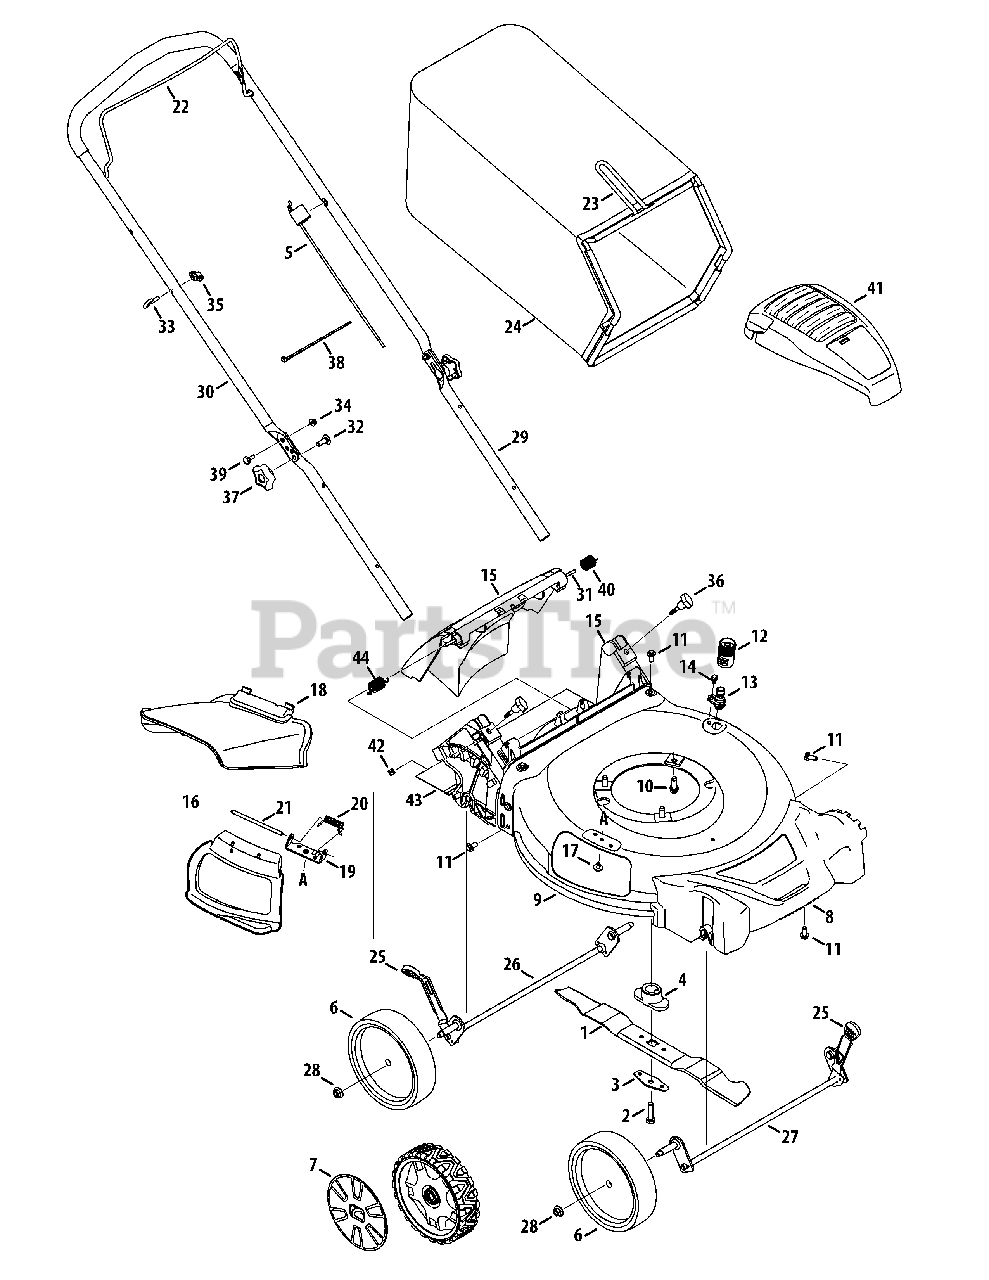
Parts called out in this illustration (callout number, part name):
1	Mulching Blade
2	Screw, 3/8-24 x 1.50
3	Blade Bell Support
4	Blade Adapter
5	Control Cable
6	Wheel, 8 x2
8	Front Cover
9	21" Deck
10	Screw, tt, 3/8-16 x 1.00
11	Screw, 5/16-14 x .750
12	Water Nozzle Adapter
13	Water Nozzle
14	Scr., Shldr., 1/4-20 x .50
15	Rear Discharge Door Assembly
16	Mulch Plug (Incl. 19-21)
18	Side Discharge Chute
19	Chute Deflector Bracket
20	Torsion Spring
22	Blade Control
23	Grass Catcher Frame
24	Grass Bag - Black
24	Grass Bag - Signature Cut Series
25	Adjustment Knob
26	Rear Axle Assembly
27	Front Axle Assembly
28	Flange Lock Nut, 3/8-16
29	Lower Handle
32	Carriage Screw ,5/16-18
33	Rope Guide
34	Nut, Flange Lock, 1/4-20
36	Wing Nut
38	Cable Tie
39	Shdr. Screw, .375 x .126 x 1/4-20
40	Torsion Spring - LH
41	Engine Shroud
41	Screw, #10-16 X 1.25
42	Nut, Sq., 1/4-20
43	Trail Shield
44	Torsion Spring - RH
